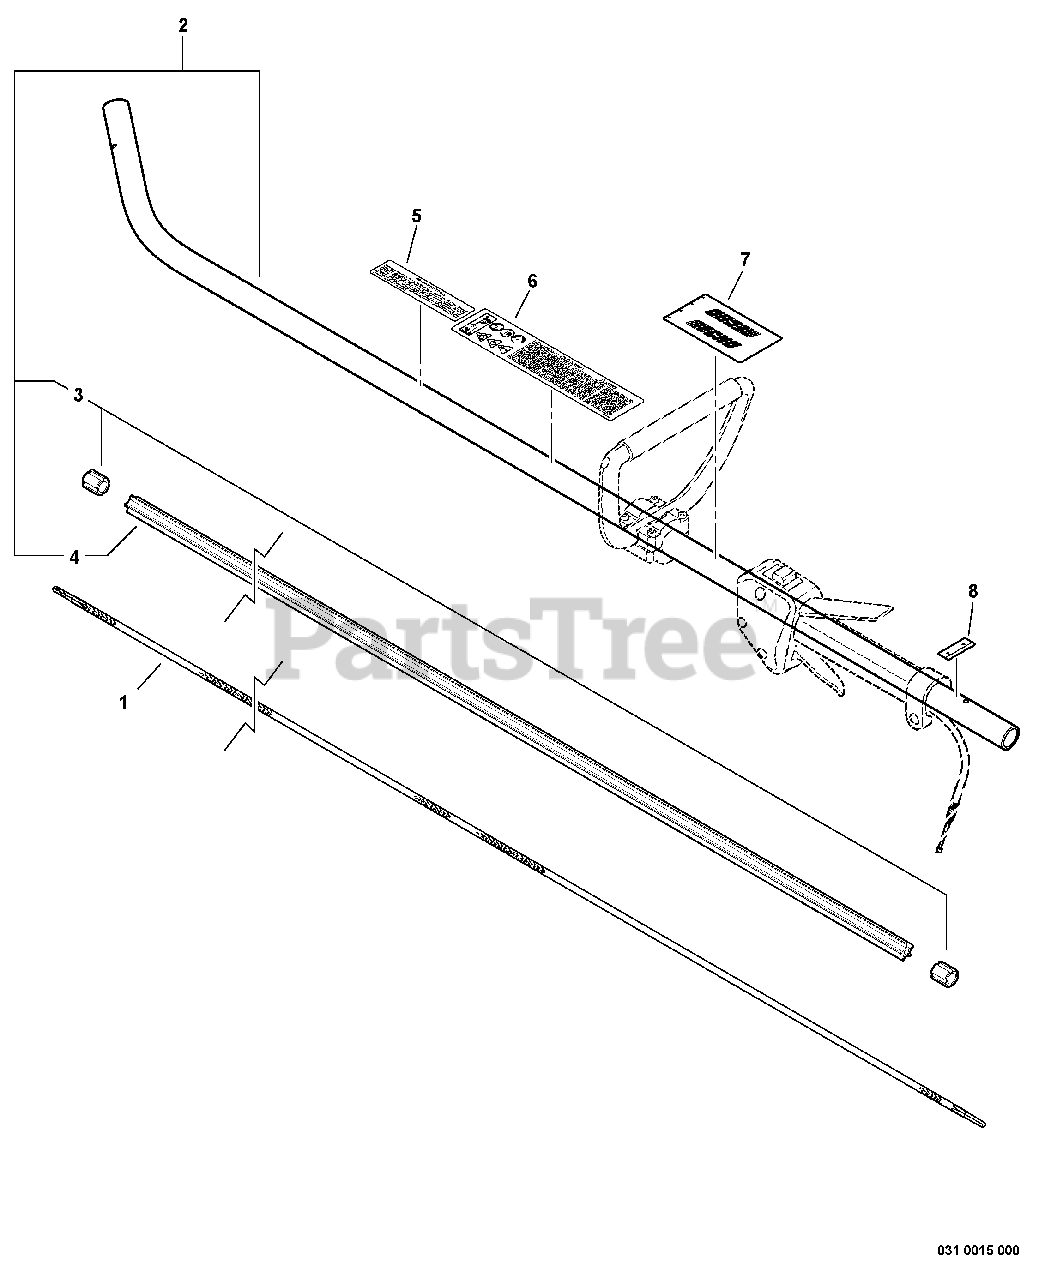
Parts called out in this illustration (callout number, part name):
1	DRIVESHAFT - FLEXIBLE
2	MAIN PIPE ASSY
4	LINER - FLEXIBLE
5	LABEL - CAUTION -- SPANISH
6	LABEL - CAUTION
7	LABEL - HANDLE LOCATION
8	LABEL - ALIGNMENT
